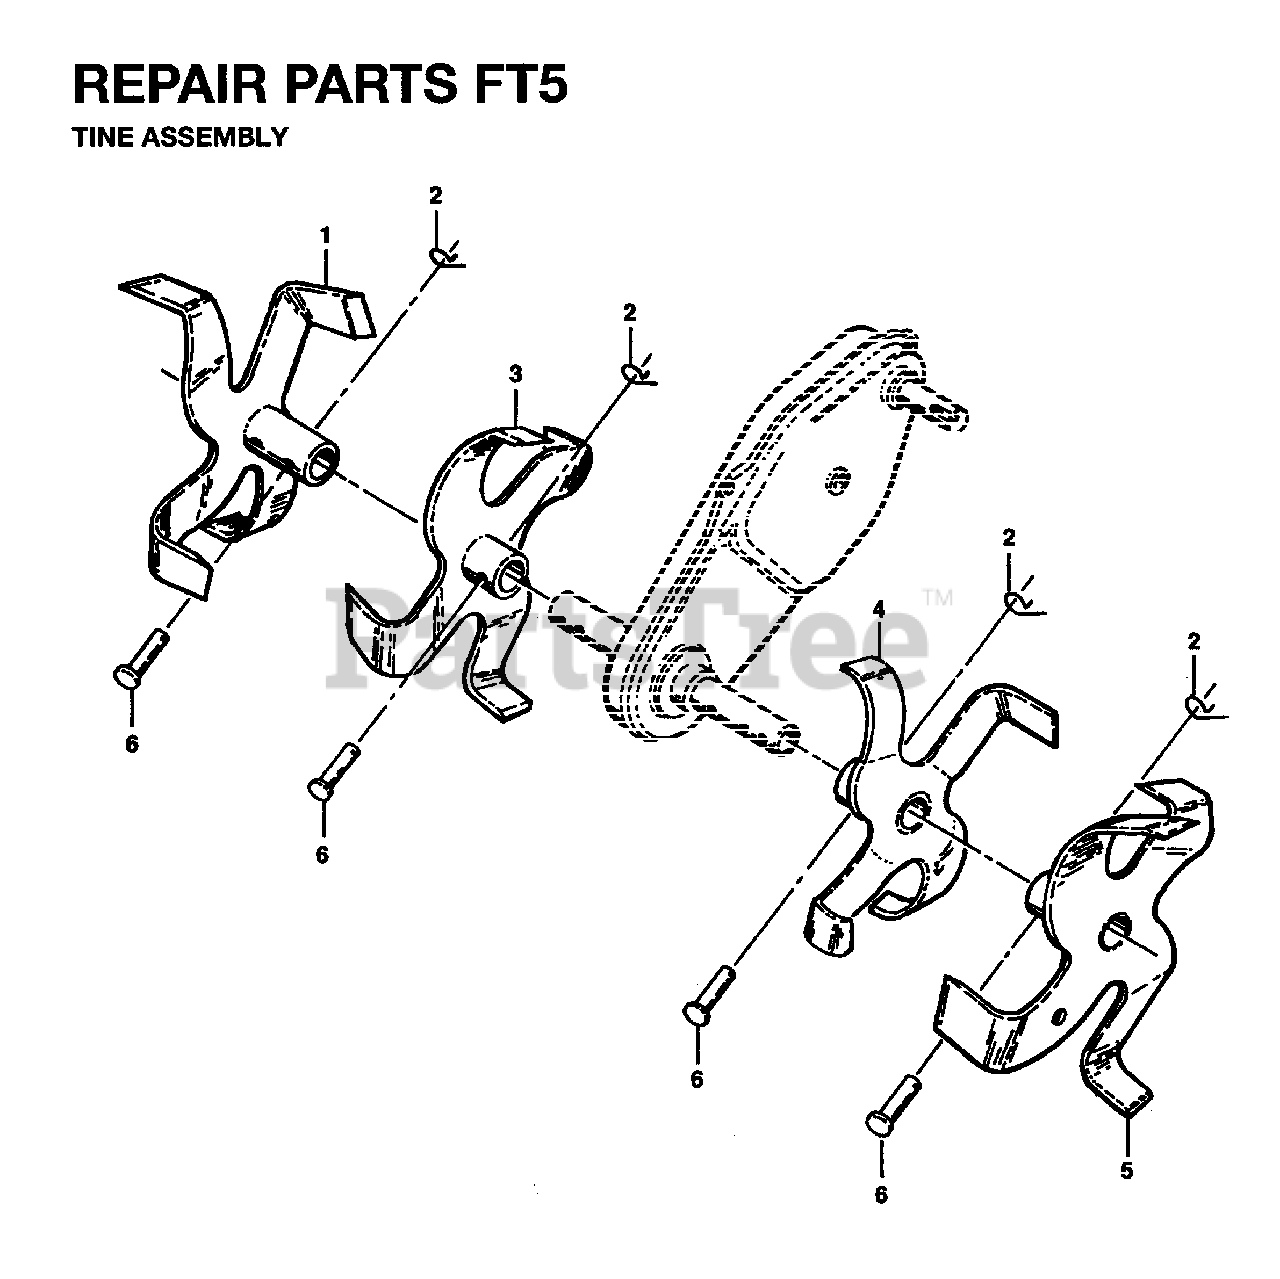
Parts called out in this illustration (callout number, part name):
1	TINE.LH.12"
2	CLEVIS PIN
3	TINE.LH.12"
4	SPRING RETAINER
5	HUB & PLATE ASM LH
6	NUT
7	WASHER, LOCK 3/8
8	BOLT.HEX.001X20.37-24X1.ZINC
9	TINE.RH.12"(72R)
10	HUB & PLATE ASM RH
11	TINE.RH.12"(72R)
